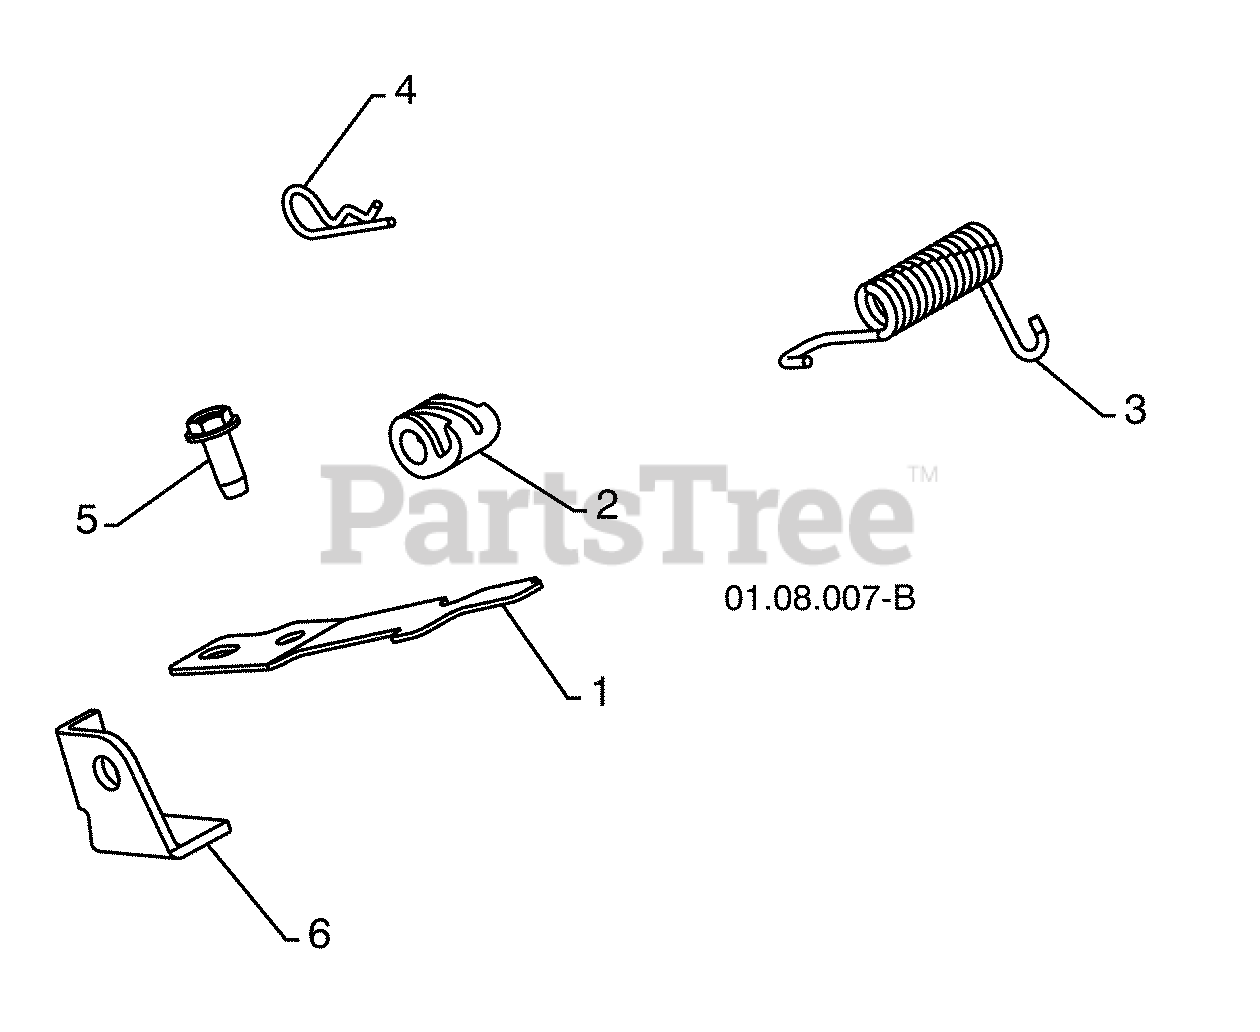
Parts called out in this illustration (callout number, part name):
1	INTERLOCK SPRING
2	INTERLOCK CAM
3	TORSION SPRING
5	SCREW 1/4--20 X .625
6	INTERLOCK STOP
